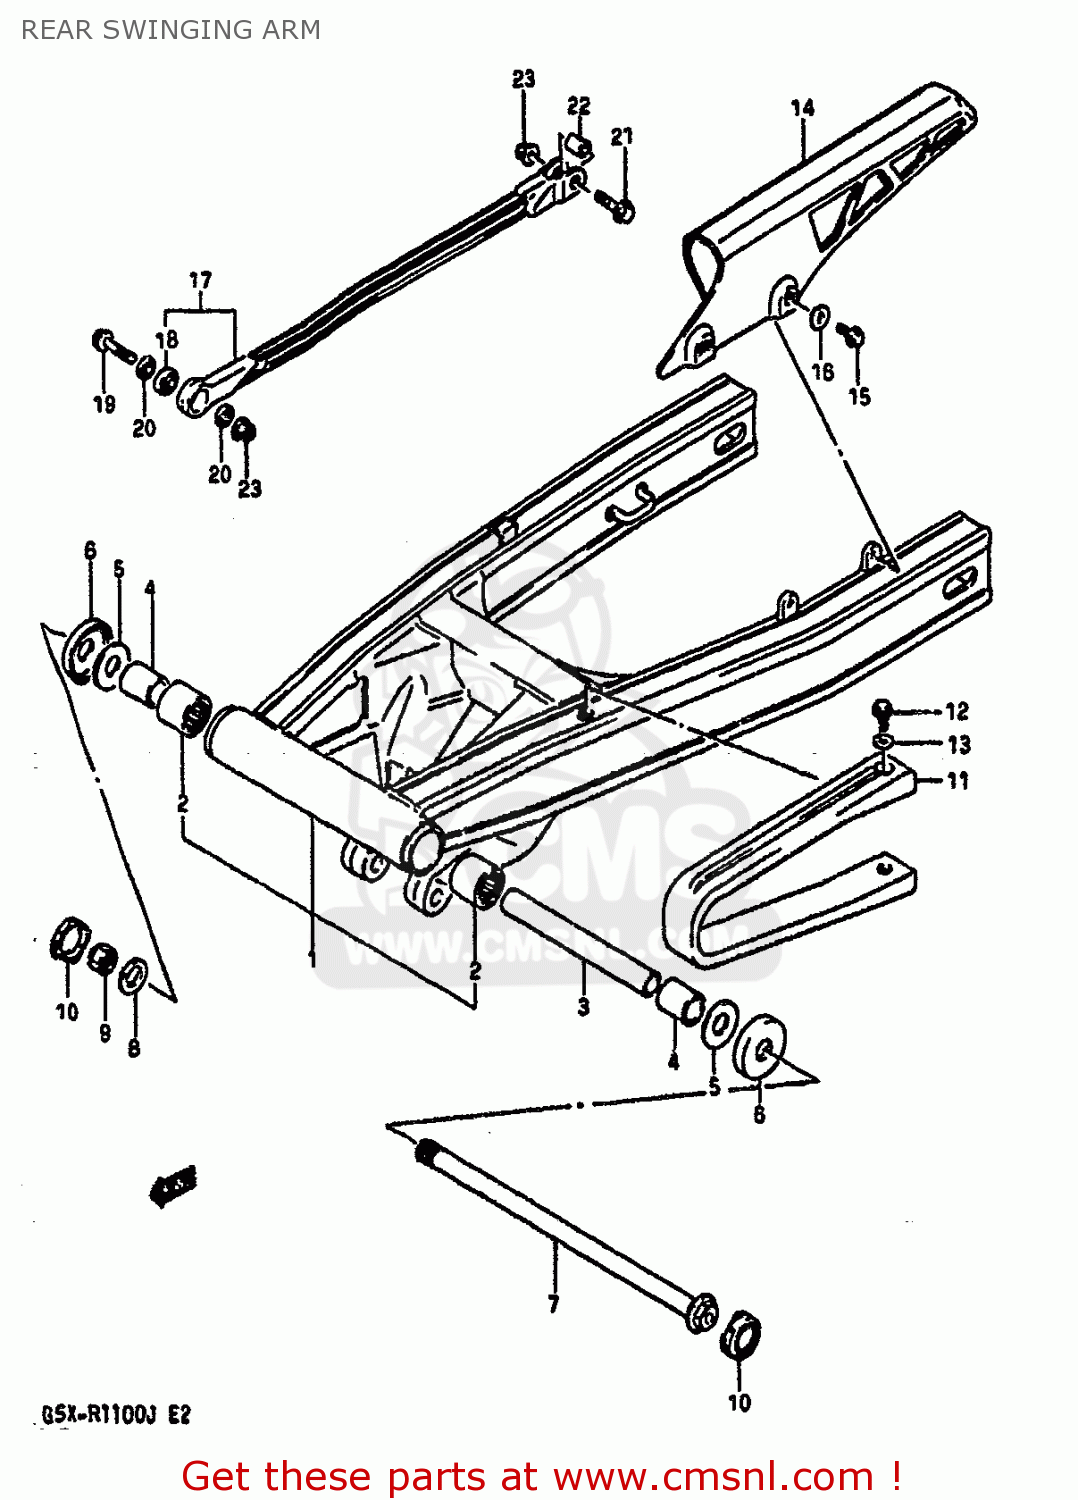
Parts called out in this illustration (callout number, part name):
1	ARM,REAR SWING
2	BEARING(25X33X30)
3	SPACER,REAR SWING ARM PIVOT
4	SPACER,RR SWGARM PIVOT
5	WASHER
6	COVER,RR SWINGINGARM PIVOT
7	SHAFT,RR SWINGINGARM PIVOT
8	WASHER(14X27X3)
9	NUT
10	CAP,SWINGINGARM PIVOT
11	BUFFER,CHAIN TOUCH DEFENSE
12	BOLT 6X20
13	WASHER
14	CASE,CHAIN
15	BOLT
16	WASHER
17	TORQUE LINK SET,REAR
18	SPHERICAL BEARING,TORQUE
19	BOLT(8X35)
20	21
21	BOLT(8X35)
22	SPACER,RR TORQUE LINK RR
23	NUT
